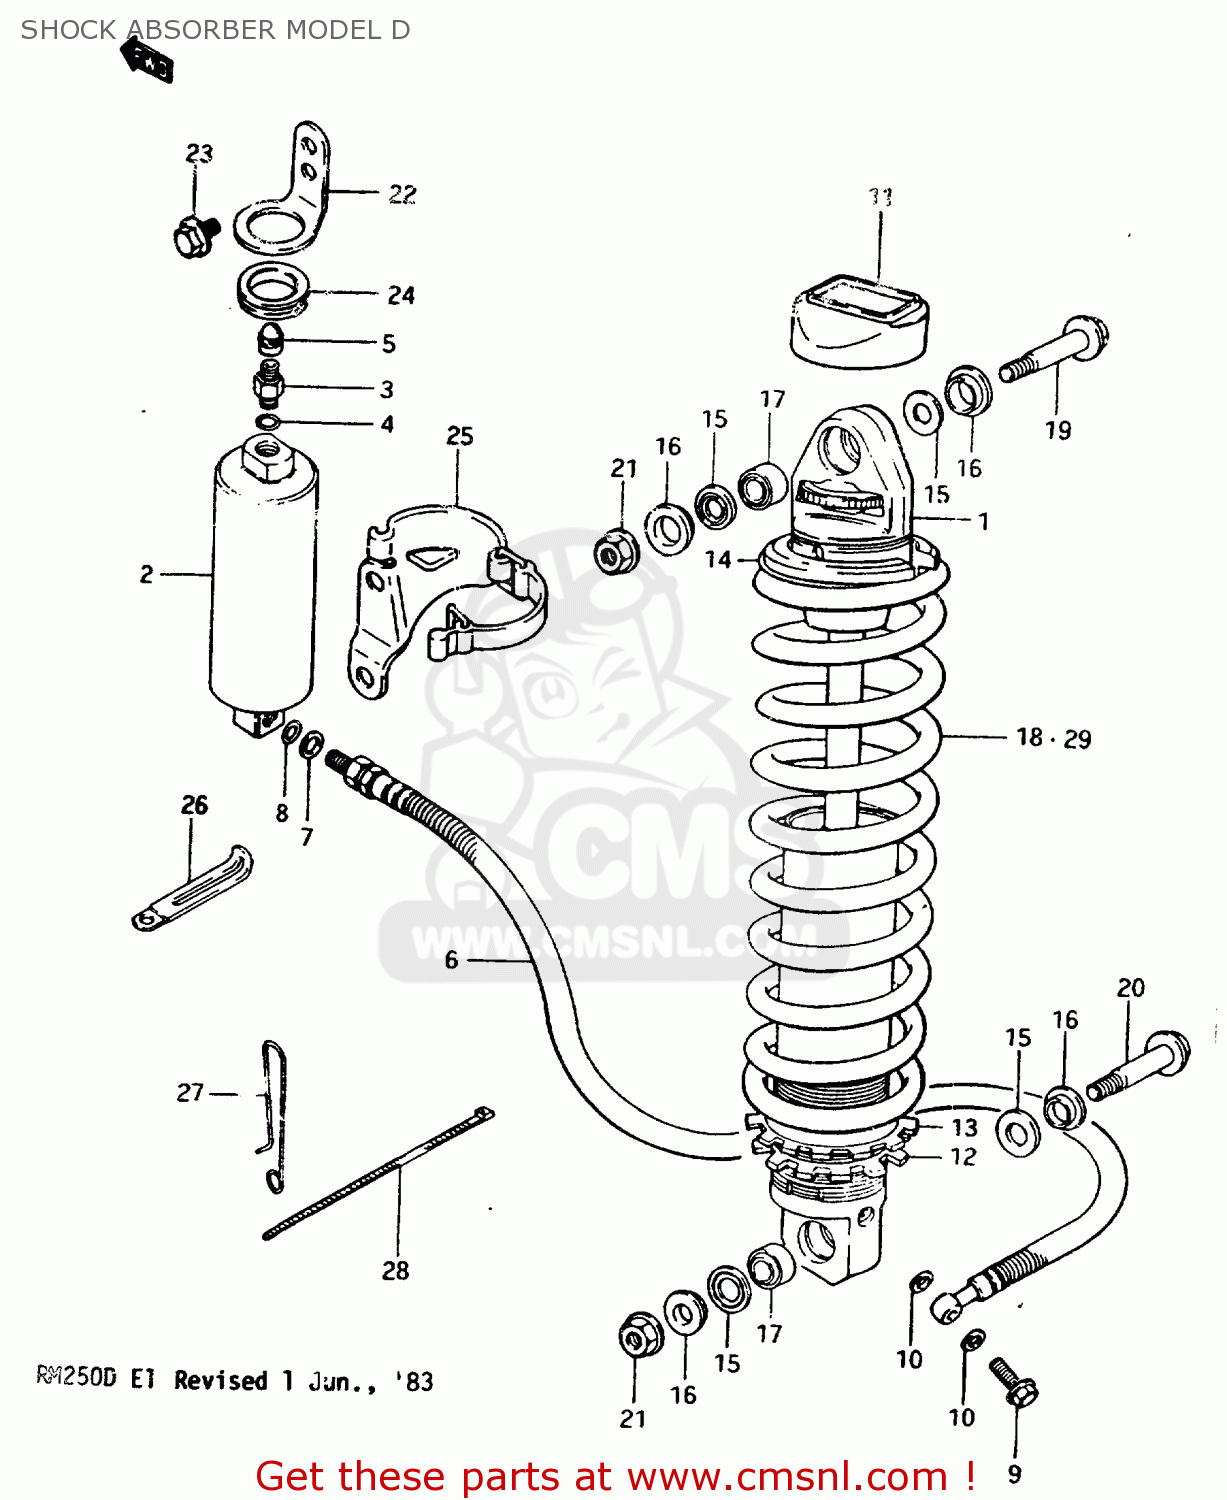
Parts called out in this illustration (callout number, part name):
1	ABSORBER ASSEMBLY,REAR SHOCK
2	RESERVE TANK,REAR SHOCK
3	VALVE,FRONT FORK AIR
4	O-RING
5	CAP
6	HOSE,REAR SHOCK ABSORBER
7	WASHER,REAR SHOCK HOSE
8	O-RING,RESERVE TANK
9	BOLT,REAR SHOCK ABSORBER
10	GASKET (NAS)
11	CAP
12	GUIDE,SPRING
13	SPRING GUIDE
14	GUIDE,REAR SHOCK ABSORBER SPRING
15	DUST SEAL,LWR
16	COLLAR
17	BEARING
18	SPRING
19	BOLT
20	BOLT(10X54)
21	NUT
22	BRACKET,RESERVOIR TANK
23	BOLT
24	CUSHION,RESERVOIR TANK
25	BRACKET,RESERVOIR TANK
26	CLAMP
27	GUIDE RES HOSE CLAMP
28	CLAMP
29	SPRING
